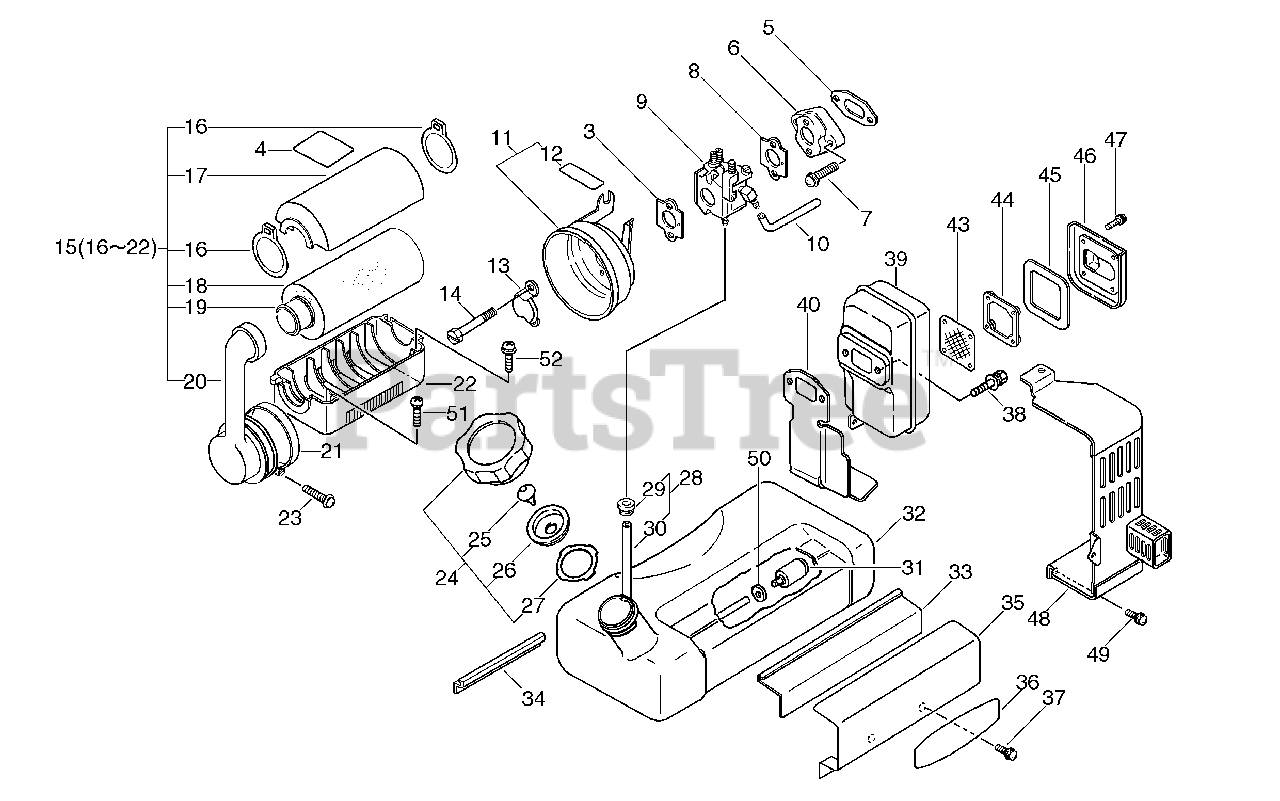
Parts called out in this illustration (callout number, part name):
3	GASKET, INTAKE
4	LABEL - CAUTION
5	GASKET, INTAKE
6	INSULATOR, INTAKE
7	SCREW - 6X25
8	GASKET, INTAKE
9	CARBURETOR WT-410C
10	PIPE - IMPULSE
11	CASE, AIR FILTER
12	LABEL - CHOKE
13	PLATE, PREVENT
14	SCREW - 5X55
15	AIR CLEANER ASSY
17	COVER, AIR FILTER
18	FILTER, AIR
19	FILTER, AIR
20	ADAPTOR, INTAKE
22	CASE, AIR FILTER
23	SCREW - 5X30
24	CAP ASSY
26	HOLDER, VENT
27	GASKET, CAP
28	PIPE, FUEL - SPIRAL
30	PIPE, FUEL - SPIRAL
31	FILTER, FUEL
32	TANK, FUEL
33	CUSHION, FUEL TANK
34	CUSHION, FUEL TANK
35	BRACKET, FUEL TANK
36	LABEL - ECHO
37	SCREW - 5X10
38	SCREW - 6X20
40	GASKET, EXHAUST
43	SCREEN, SPARK ARRESTOR
44	RETAINER, SCREEN
45	GASKET, EXHAUST
46	GUIDE, EXHAUST
47	SCREW - 4X16
48	COVER, EXHAUST
49	SCREW - 5X14
50	CLIP - 6
51	SCREW - 6X15
52	SCREW - 6X20
